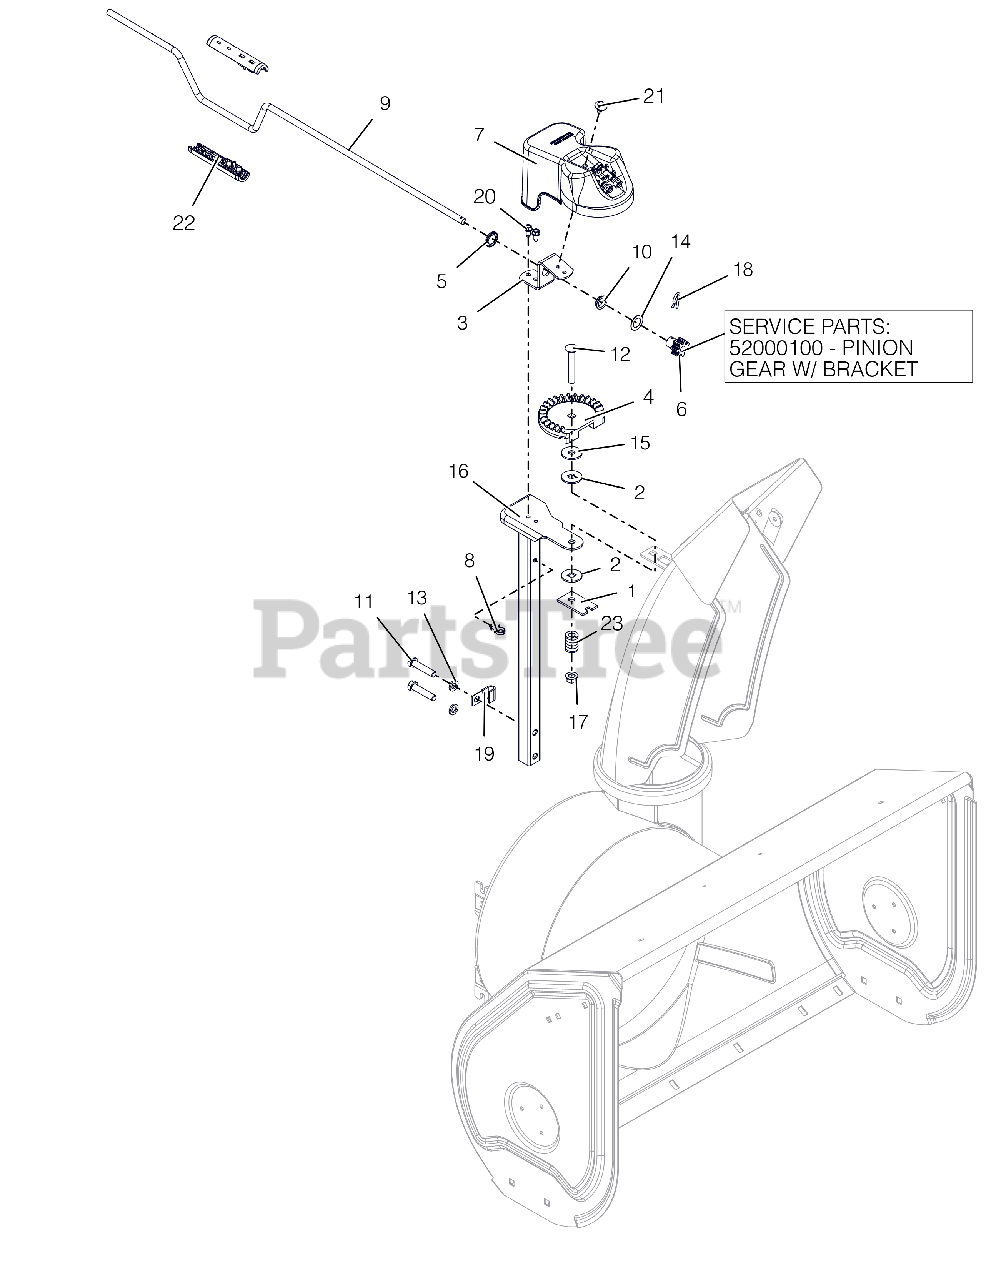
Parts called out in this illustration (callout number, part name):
1	PLATE, FRICTION
2	FRICTION WASHER
3	BRACKET, PINION GEAR
4	CHUTE GEAR
5	PUSHNUT .625
6	PINION GEAR - CHUTE
6	PINION GEAR W/BRACKET
7	GEAR COVER ASSY LG SHEAR BOLT
8	CLIP, CABLE GUIDE
9	ROD,CRANK - LGDASH DLX
10	BUSHING, POLYLINER-.63 SNAPIN
11	@BLT-HEX .38-16X1.75 GR5 YWZC
12	@BLT-RDHDSQNK .38-16X2.50 G5YZ
13	@WSHR-LK .38X.094 REG YWZC
14	WSHR-THRST .625 X 1.0 X .03
15	@WSHR-FL-STL .406X1.25X.10 ZC
16	PEDESTAL, CHUTE - CRANK
17	@NUT-LK-TOP-FLG .38-16 YWZC
18	PIN, SPRING CLIP
19	J-CLAMP
20	SCR-TAP .25-20X.50 HWH TR YWZ
21	SCR-TAP .25-20X.50 LGHWH TR YZ
22	KNOB,CHUTE CRANK-DELUXE
23	SG-COMP .187X.56X1.62
